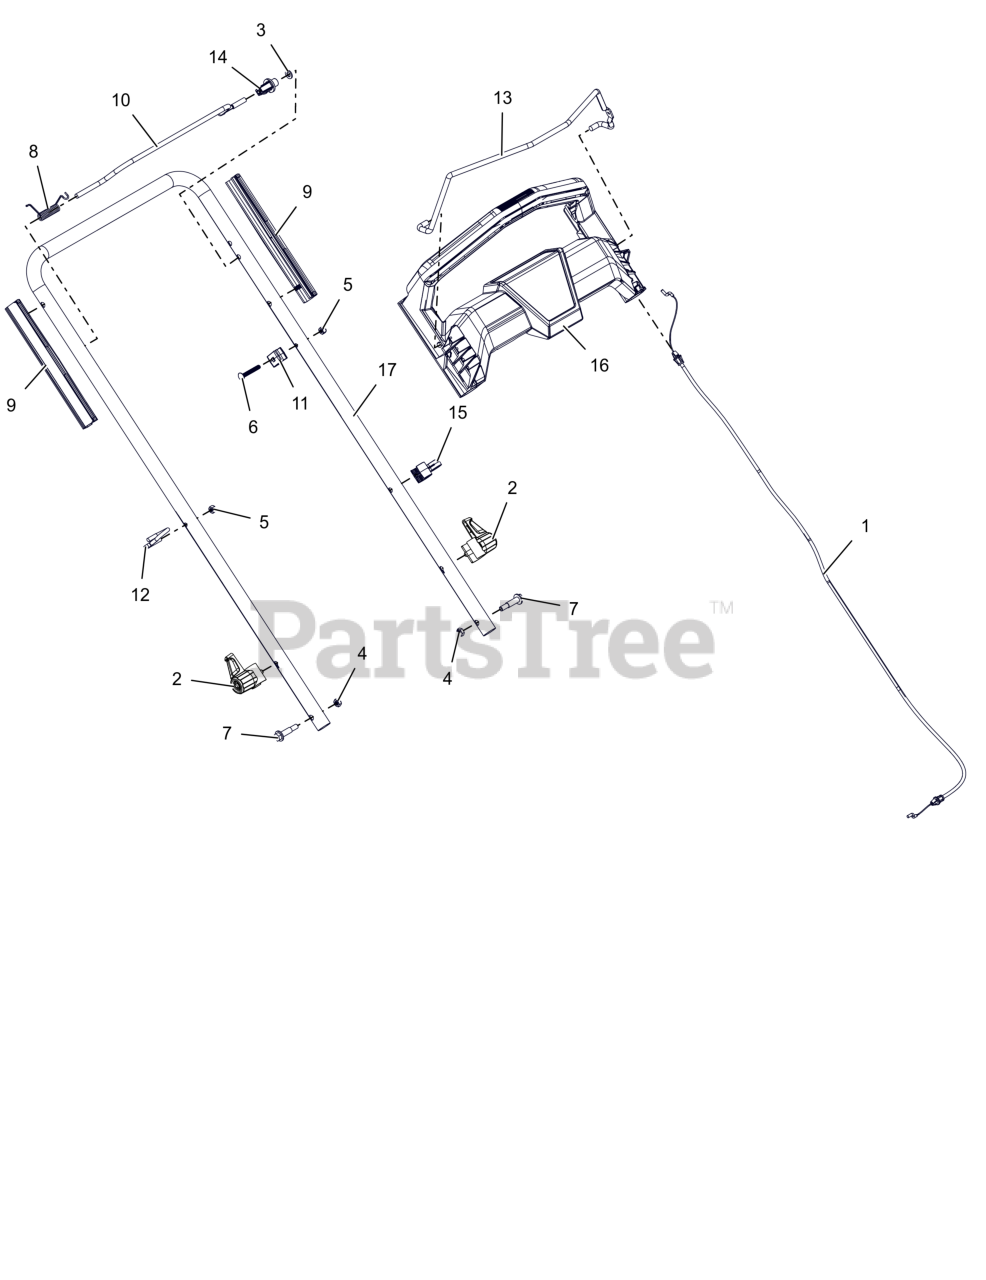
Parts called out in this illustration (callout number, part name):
1	CABLE, RWD OP
2	ASM, HANDLE ADJUSTER
3	WSHR-FL-STL, .328 X .625 X .051
4	NUT, NYLOC 5/16-18
5	NUT, NYLOC 1/4-20
6	BOLT, CARRIAGE 1/4-20X1.75
7	BLT, SHLDR HWH .65X1.015X 5/16-18
8	SPRG, TORSION - REFLEX
9	GUIDE, HANDLE - REFLEX
10	BAIL, REFLEX
11	CLAMP, CABLE - TRANSMISSION
12	GUIDE, STARTER ROPE (BLACK)
13	BAIL, OPC - REFLEX (GRAY)
14	CAM, REFLEX
15	GUIDE, CABLE
16	COVER, HANDLEBAR - REFLEX
17	HANDLEBAR, REFLEX (BLACK)
